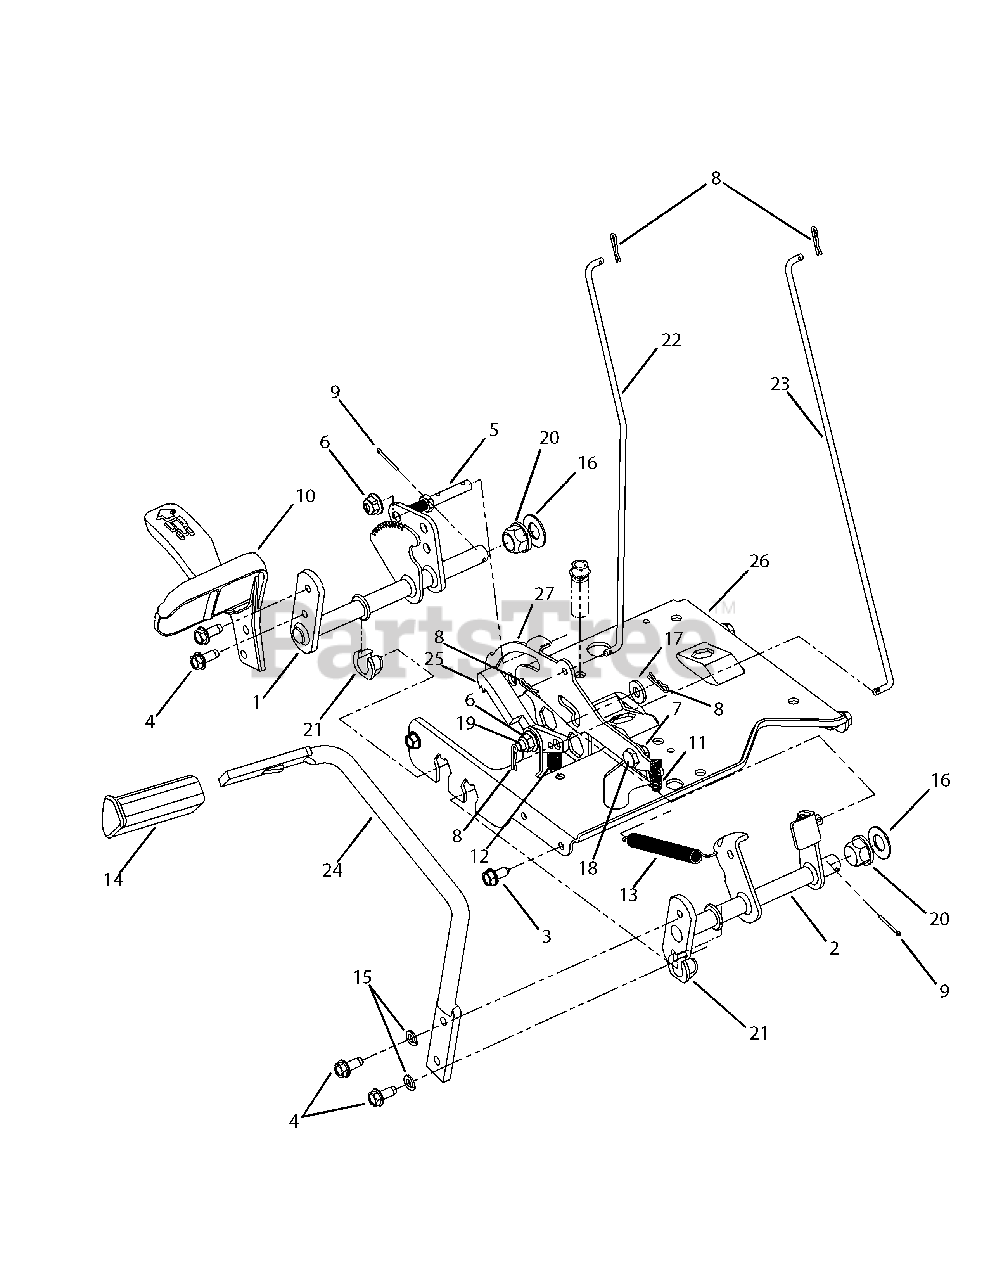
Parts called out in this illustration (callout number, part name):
4	Screw, Self-tapping, 5/16-18, 0.75
5	Pin, 3/8-16, 3/8 x 2.68
6	Nut, Nylon Lock, 3/8-16
7	Nut, Flange Lock, 5/16-18, Gr5
8	Pin, Cotter, .072 Dia. x 1.13 Lg
9	Pin, Cotter, 3/32, 1.0
11	Spring, Compression, .405 x 1.17
12	Spring, Extension, .50 OD x 1.41 Lg
13	Spring, Extension, .50 Dia x 6.37 Lg
14	Pad, Brake, Control
15	Washer, Lock, 5/16
16	Washer, Flat .64 x 1.24 x .06
17	Washer, Flat, .385 x .870 x .092
18	Shoulder, Screw .437
19	Shoulder, Screw 3/8-16
20	Bearing, Hex Flange
21	Bearing, Hex Flange, .628 ID, Split
22	Rod, Control, Brake Lock
23	Rod, Control, Cruise
27	Bracket, Lockout, Hydro
